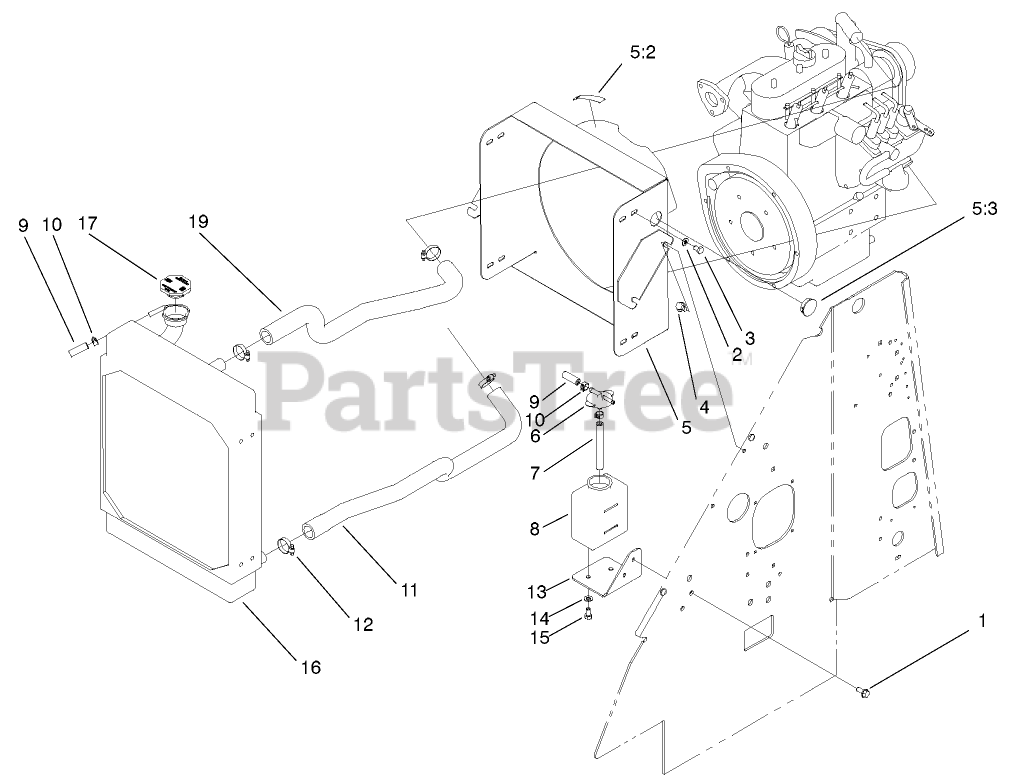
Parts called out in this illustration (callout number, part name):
1	SCREW-HWHTF
2	WASHER-FLAT
3	SCREW-HH
4	SCREW-HWHTF
5	MOUNT-RADIATOR
5:2	DECAL-WARNING, FAN
5:3	PLUG-HOLE
6	CAP-TANK, OVERFLOW
7	HOSE-FUEL
8	TANK-OVERFLOW
9	HOSE-FUEL
10	CLAMP-HOSE
11	HOSE-RADIATOR, LOWER
12	CLAMP-HOSE
13	MOUNT-TANK, OVERFLOW
14	WASHER-PLAIN
15	BOLT
16	RADIATOR
17	CAP-RADIATOR
19	HOSE-RADIATOR, UPPER
